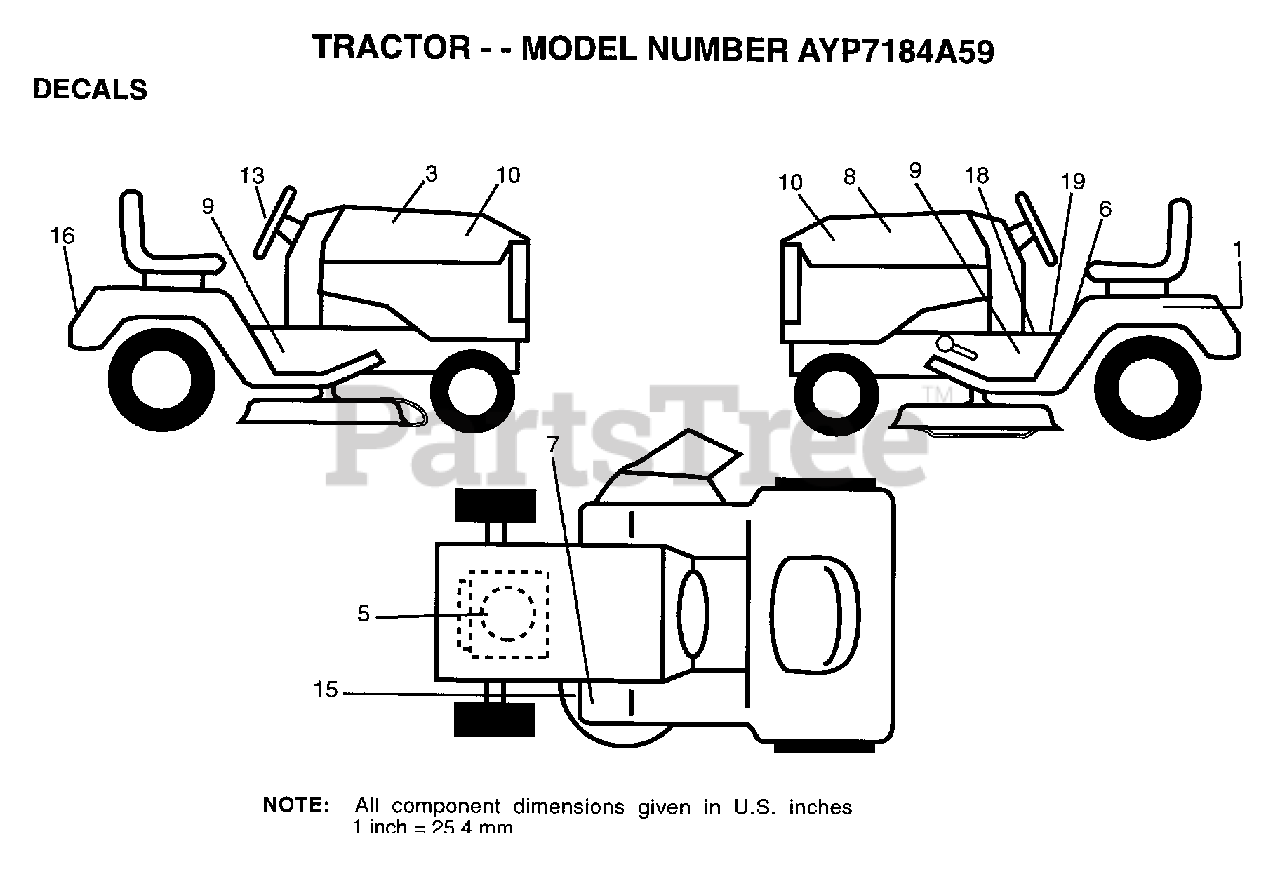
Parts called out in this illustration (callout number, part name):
1	DECAL.BATRY.3-3908
3	DECAL.HD.RH.WIZAR
5	DECAL B&S 18 HP OPLLN/IC
6	DECAL
8	DECAL.HD.LH.WIZAR
9	DECAL CHASSIS WIZ
10	DECAL INS HOOD
13	DECAL.INS.STRG.WL
15	DECAL
18	DECAL BRAK PARK
